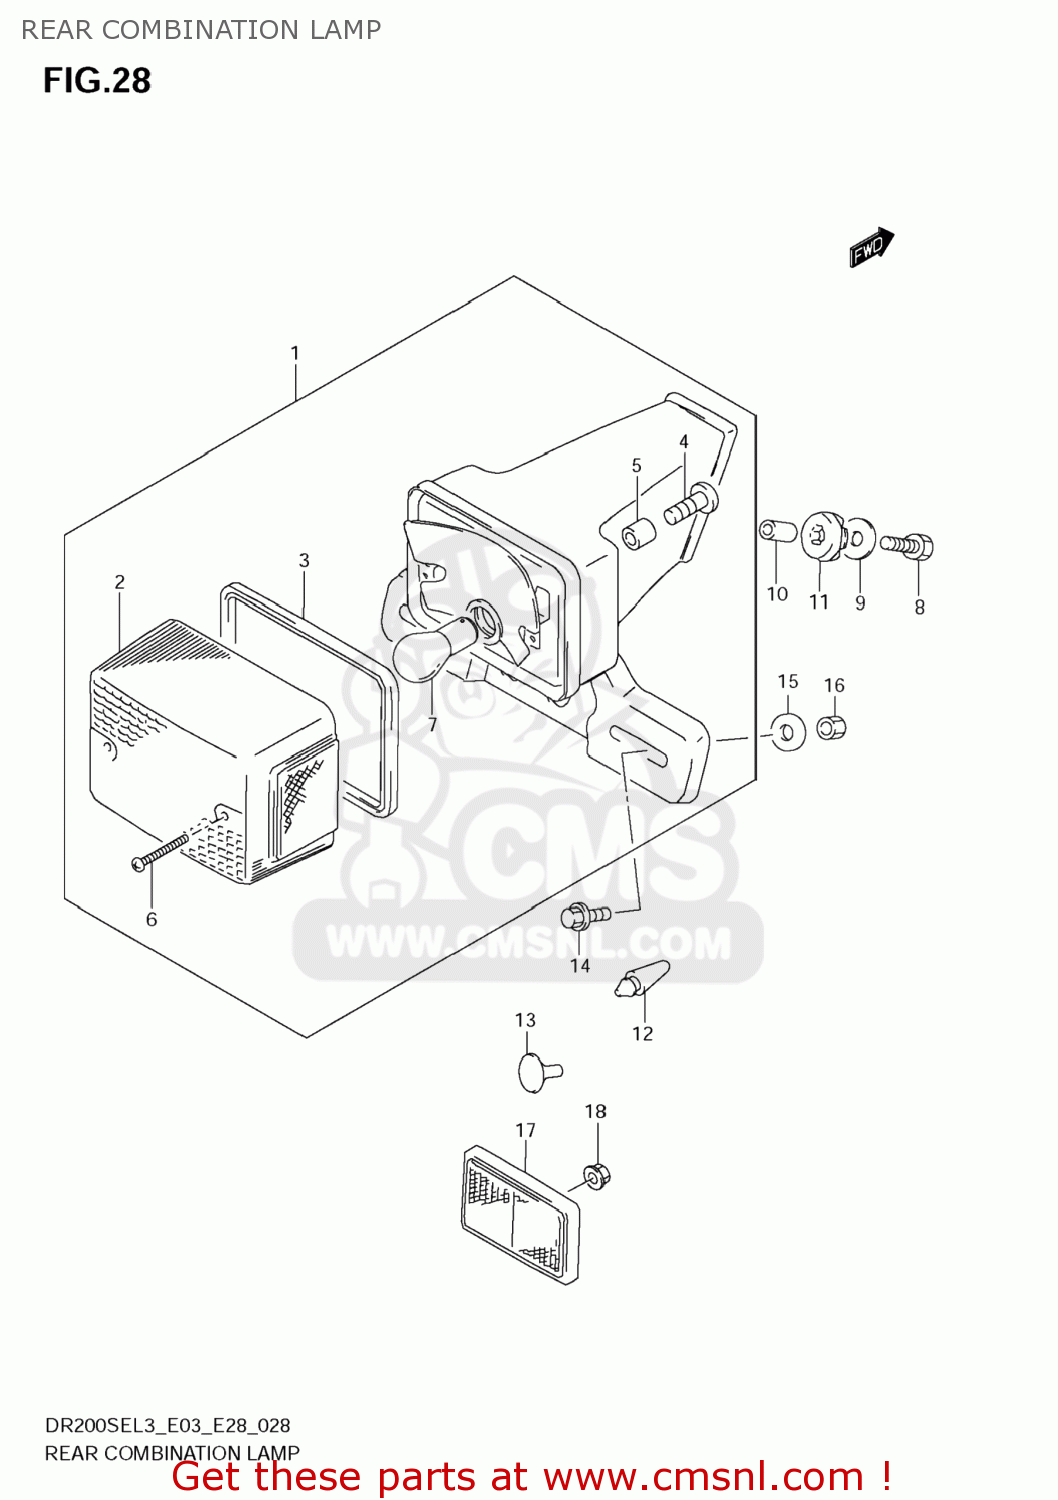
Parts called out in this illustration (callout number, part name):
1	LAMP ASSY,RR COMBINATION
2	LENS
3	GASKET,LENS (NAS)
4	SCREW(6X25)
5	SPACER
6	SCREW(4X45)
7	BULB(12V21/5W)
8	BOLT
9	WASHER(6.5X18X1.6)
10	SPACER(6.5X10X13)
11	CUSHION
12	CUSHION
13	CUSHION
14	BOLT
15	WASHER(6.5X18X1.6)
16	NUT
17	REFLECTOR ASSY,RR
18	NUT
